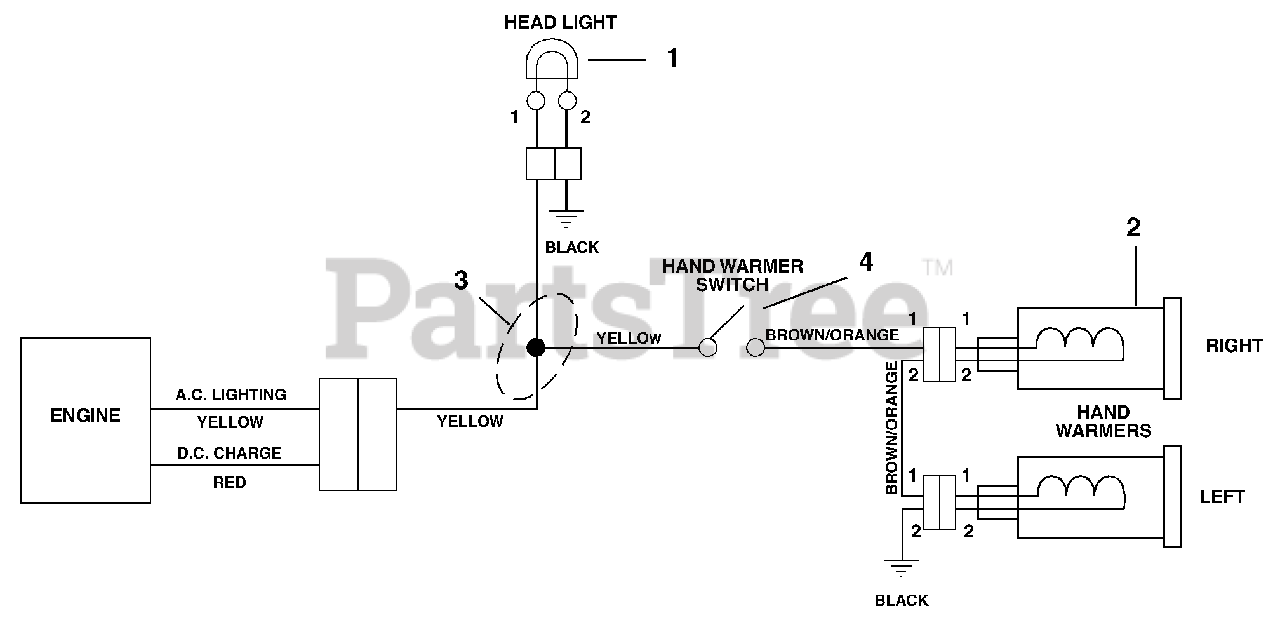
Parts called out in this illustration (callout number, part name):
1	HEADLAMP, OVAL W/ 1156 BULB
2	WARMER, HAND W/TERMINAL
3	WIRE HARNESS-HOT GRIPS & LIGHT
4	SWITCH, ON/OFF
